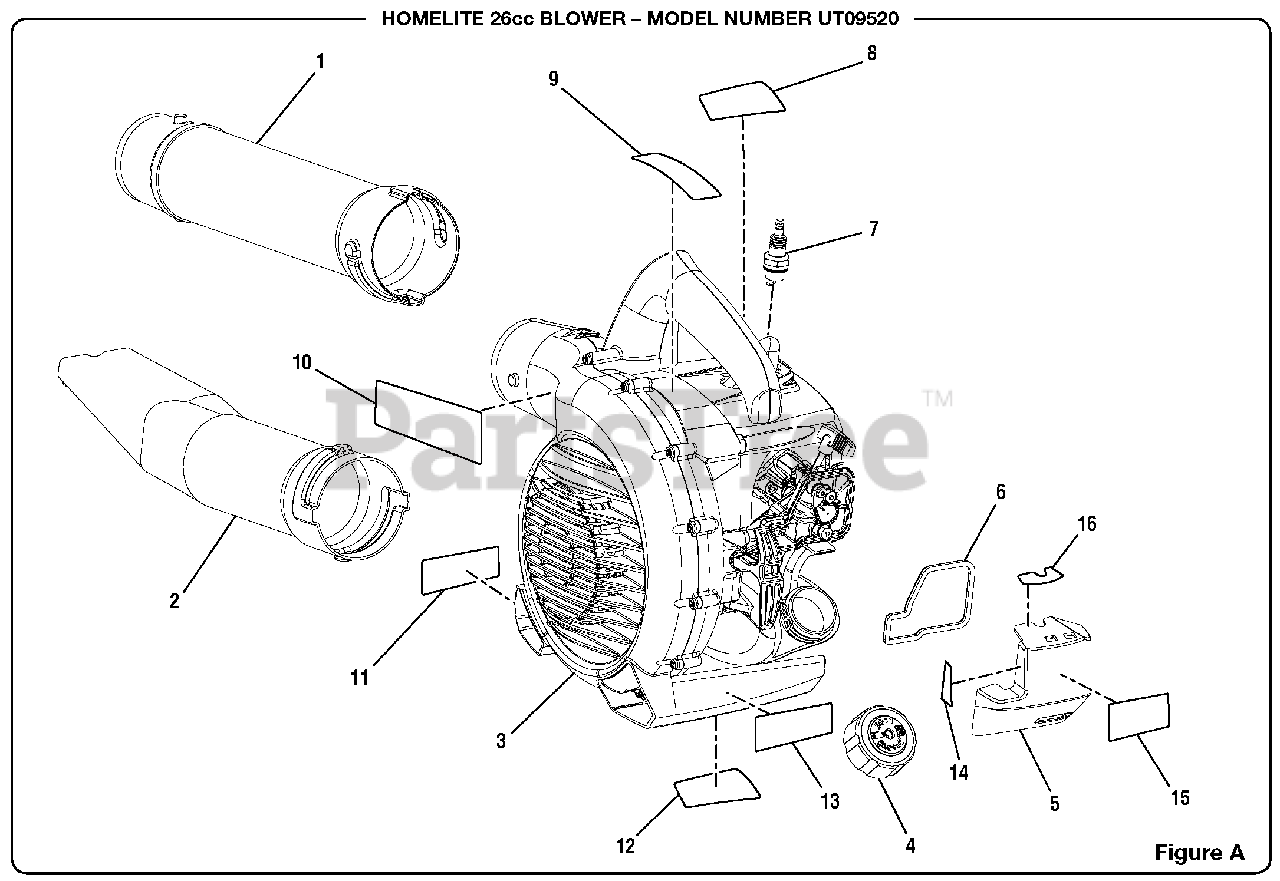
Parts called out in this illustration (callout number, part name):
1	Blower Tube
2	High Velocity Nozzle w/Leaf Scraper
3	Blower Assembly
4	Fuel Cap Assembly
5	Air Box Cover
6	Air Box Gasket
7	Spark Plug (RCJ6Y)
9	Warning Label
10	Logo Label
11	Combustion Warning Label
12	Emissions Label
13	MPH Label
14	Choke Label
15	Starting Instructions Label
16	Throttle Label
